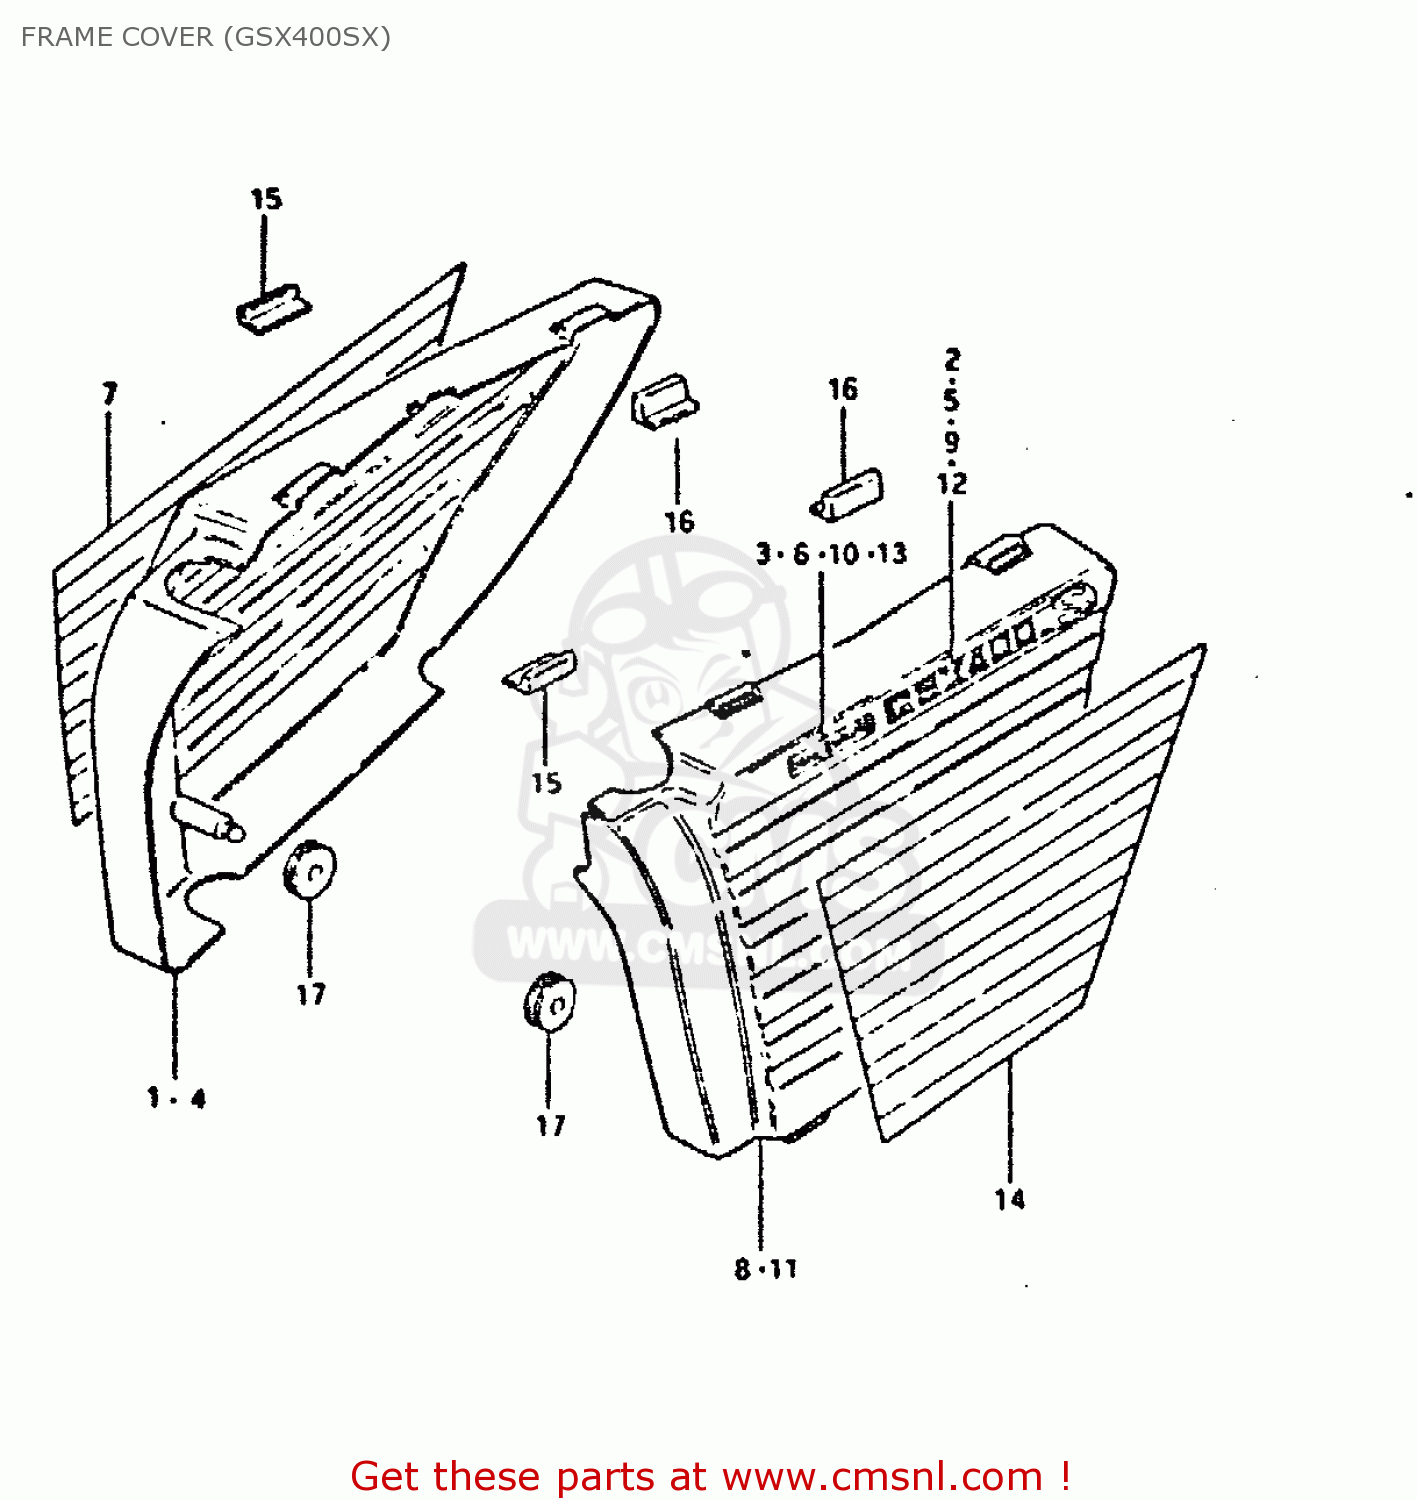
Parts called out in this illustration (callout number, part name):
1	COVER,FRAME,RIGHT
2	EMBLEM, "GSX400S"
3	EMBLEM (WHITE)
4	COVER, FRAME RH (WHITE)
5	EMBLEM, "GSX400S"
6	EMBLEM (BLACK)
7	TAPE SET, RH
8	COVER,FRAME,LEFT
9	EMBLEM, "GSX400S"
10	EMBLEM (WHITE)
11	COVER, FRAME LH (WHITE)
12	EMBLEM, "GSX400S"
13	EMBLEM (BLACK)
14	TAPE SET
15	CUSHION,FRAME COVER
16	CUSHION,FRAME COVER
17	CUSHION
